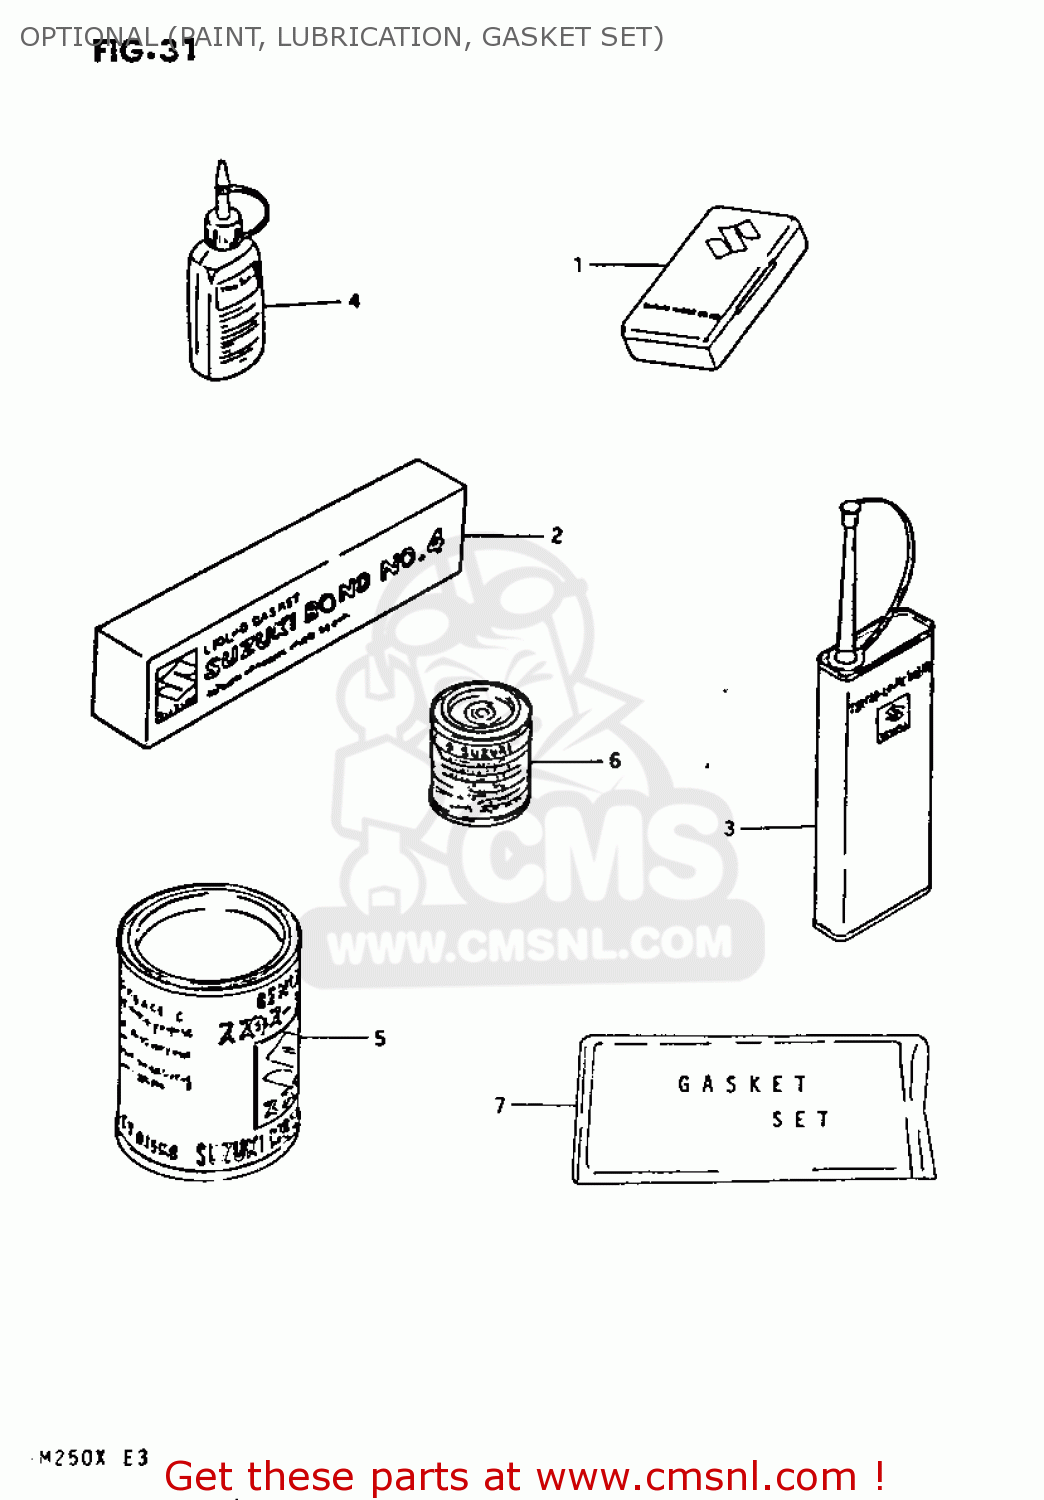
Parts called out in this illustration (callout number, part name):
1	TUBE REPARING TOOL
2	LIQUID GASKET 1
3	THREAD LOCK NO.1401 CLEAR 200G
4	THREAD LOCK NO.1303B PURPL 50G
5	GREASE(C)EP2 LITHIUM 150G
6	PAINT,BLACK
7	GASKET SET
